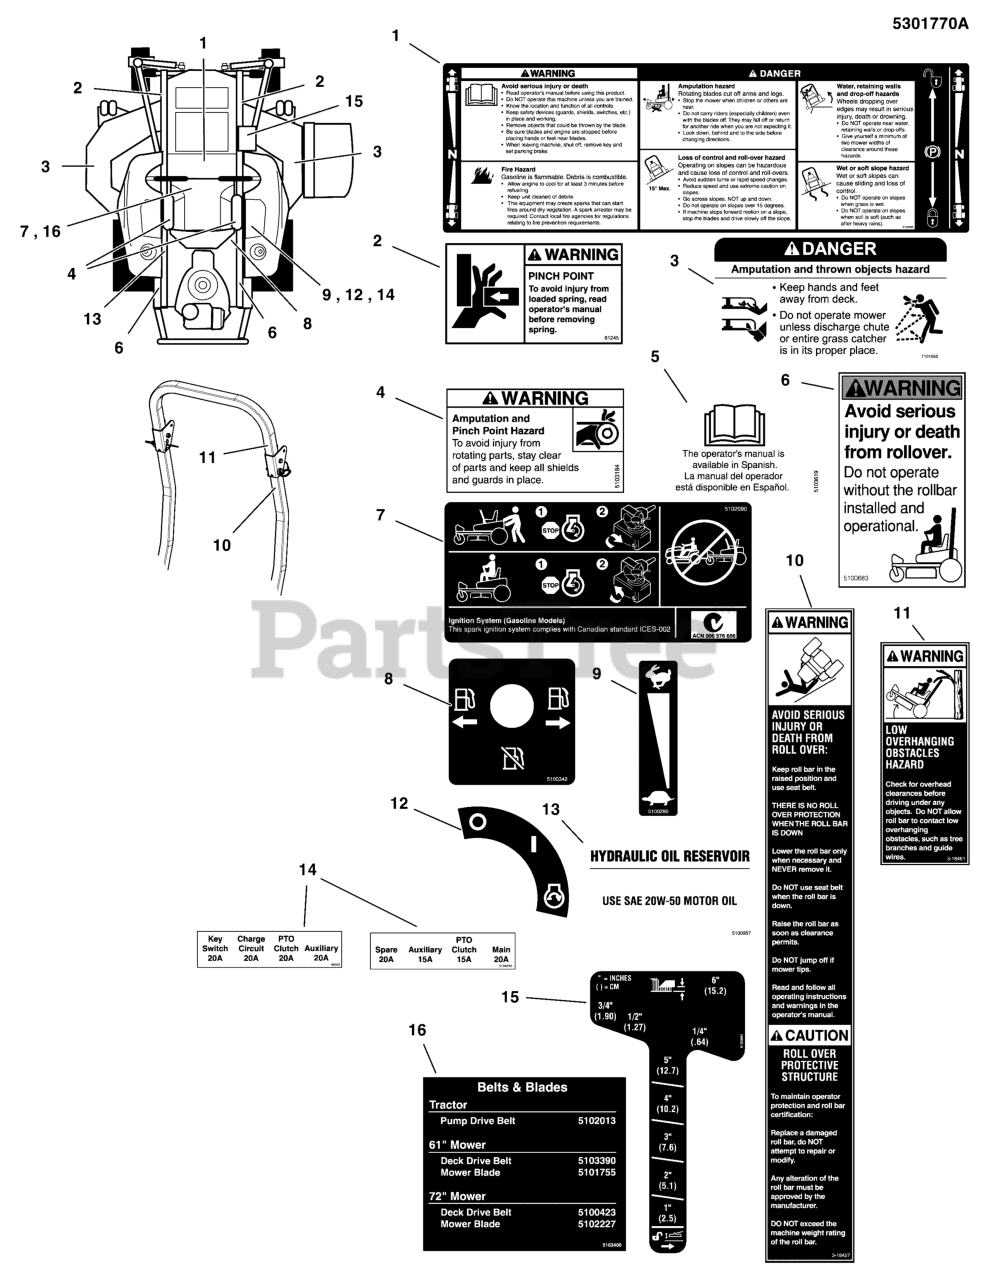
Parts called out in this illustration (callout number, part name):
1	DECAL, MAIN SAFETY
2	DECAL, PINCH POINT
3	DECAL, DANGER DO NOT OPERATE W/O DEFLECT
4	DECAL, WARNING, HAND IN BELT, ENG ONLY
5	DECAL, MANUAL AVAIL IN SPANISH
6	DECAL, WARNING, ROLL BAR
7	DECAL, TRANSAXLE RELEASE, S200XT
8	DECAL, FUEL VALVE
9	DECAL, THROTTLE CONTROL
11	DECAL, WARNING & CAUTION, ROPS
12	DECAL, IGNITION SWITCH
13	DECAL, HYDRAULIC OIL, SAE 20W50
14	DECAL, FUSE LOCATION, 20-20-20-20
14	DECAL, FUSE LOCATION, 20-15-15-20
15	DECAL, DECK HEIGHT, 1-1/2 TO 6, S200XT
16	DECAL, BELT & BLADE, S200XT
